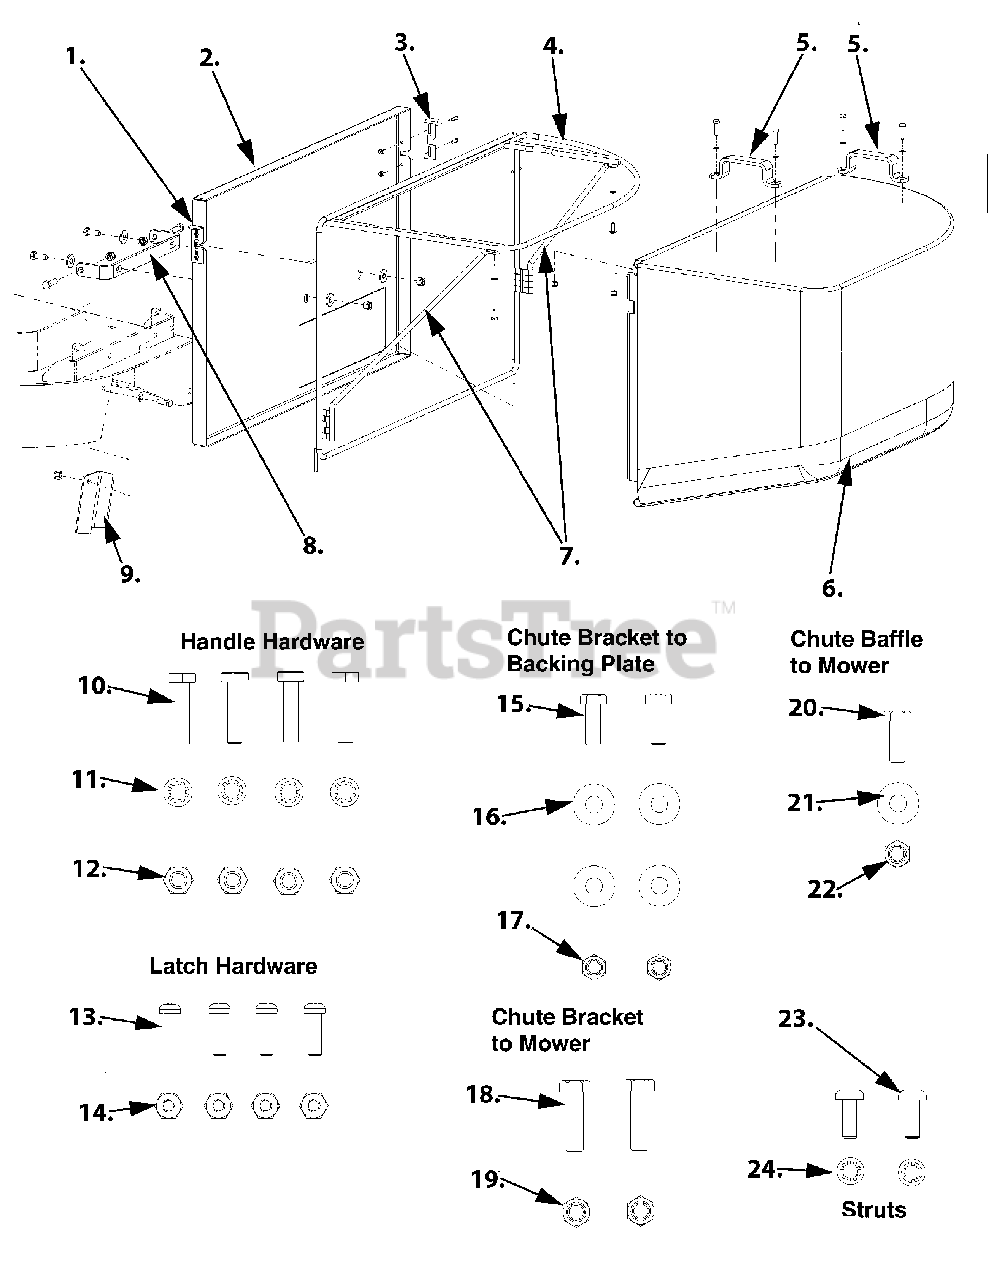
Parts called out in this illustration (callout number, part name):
7	Struts
11	Internal Tooth Washers
12	Nylock Nuts 1/4-20
13	Pan Head Screws 10-32 x 5/8
14	Nylock Nuts 10-32
15	Screw, Hex Cap, 3/8-16 x 1.00
16	Flat Washers 3/8
17	Nylock Nuts 3/8-16
18	Screw, Hex Cap, 3/8-16 x 1.25
19	Nylock Nuts 3/8-16
20	Screw, Hex Cap, 5/16-18 x 1.00
21	Flat Washers 5/16
22	Nylock Nuts 5/16-18
23	Screw 1/4-20 x 5/8
24	Washers
